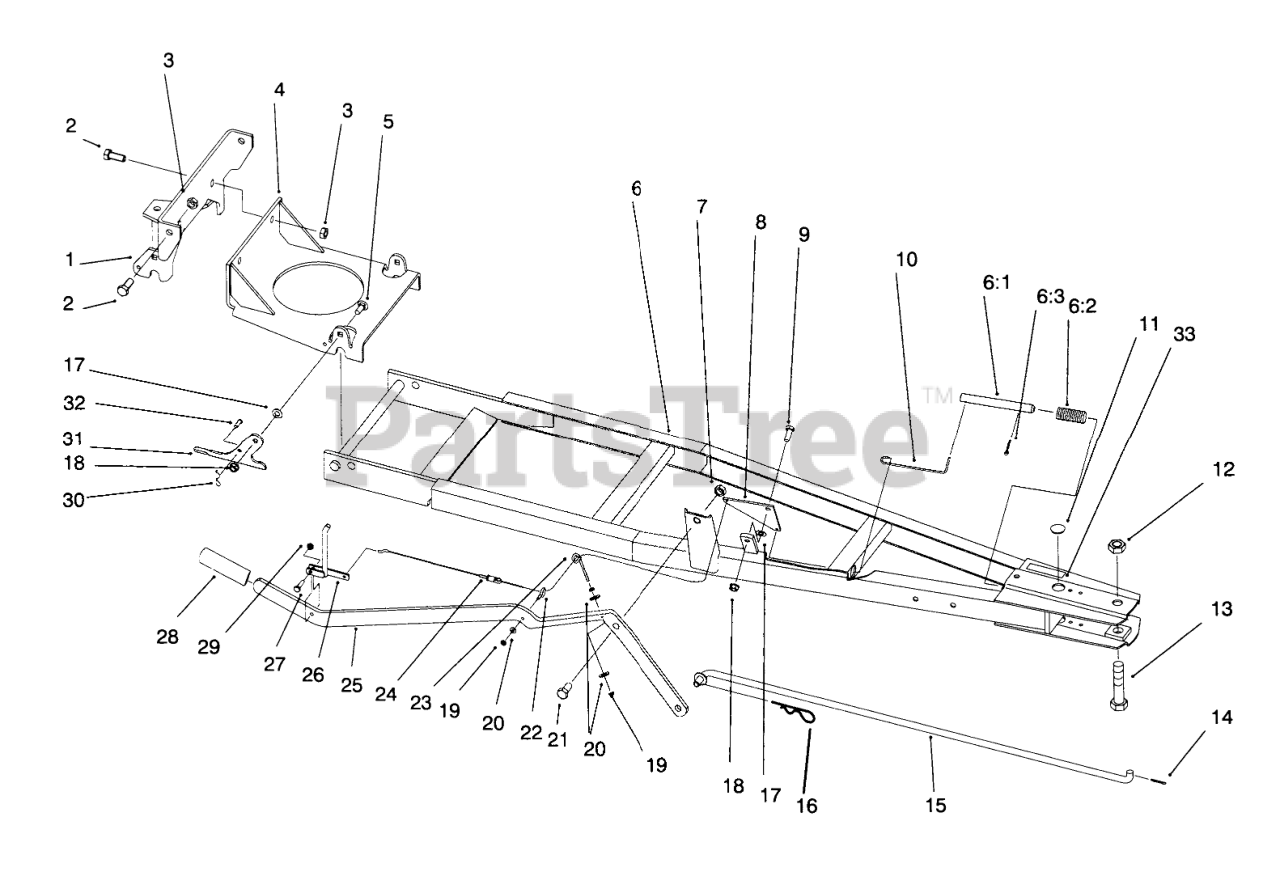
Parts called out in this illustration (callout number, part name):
1	BRACKET-MOUNTING
2	SCREW-HH
3	NUT-LOCK, NI
4	BRKT - BLDE MTG WA BLACK
5	BOLT-CARR
6	Frame
6:1	PIN-INDEX
6:2	SPRING-COMPRESSION
6:3	PIN-COTTER
7	NUT-JAM
8	PLATE - INDEX
9	SCREW-HH
10	ROD-LOWER INDEX
11	PLUG
12	NUT-LOCK
13	SCREW-HH
14	PIN-COTTER
16	PIN-HAIR
17	WASHER-FLAT
18	NUT-LOCK, NI
19	NUT-LOCK, NI
20	WASHER-FLAT
21	SCREW-HH
22	EYEBOLT
23	EYELET - CABLE
24	CABLE ASM - LIFT
25	Lever-Blade
26	LEVER-INDEX
27	SCREW-HH
28	GRIP
29	NUT-LOCK
30	PIN-HAIR
31	PLATE-LATCHING
32	PIN-CLEVIS
